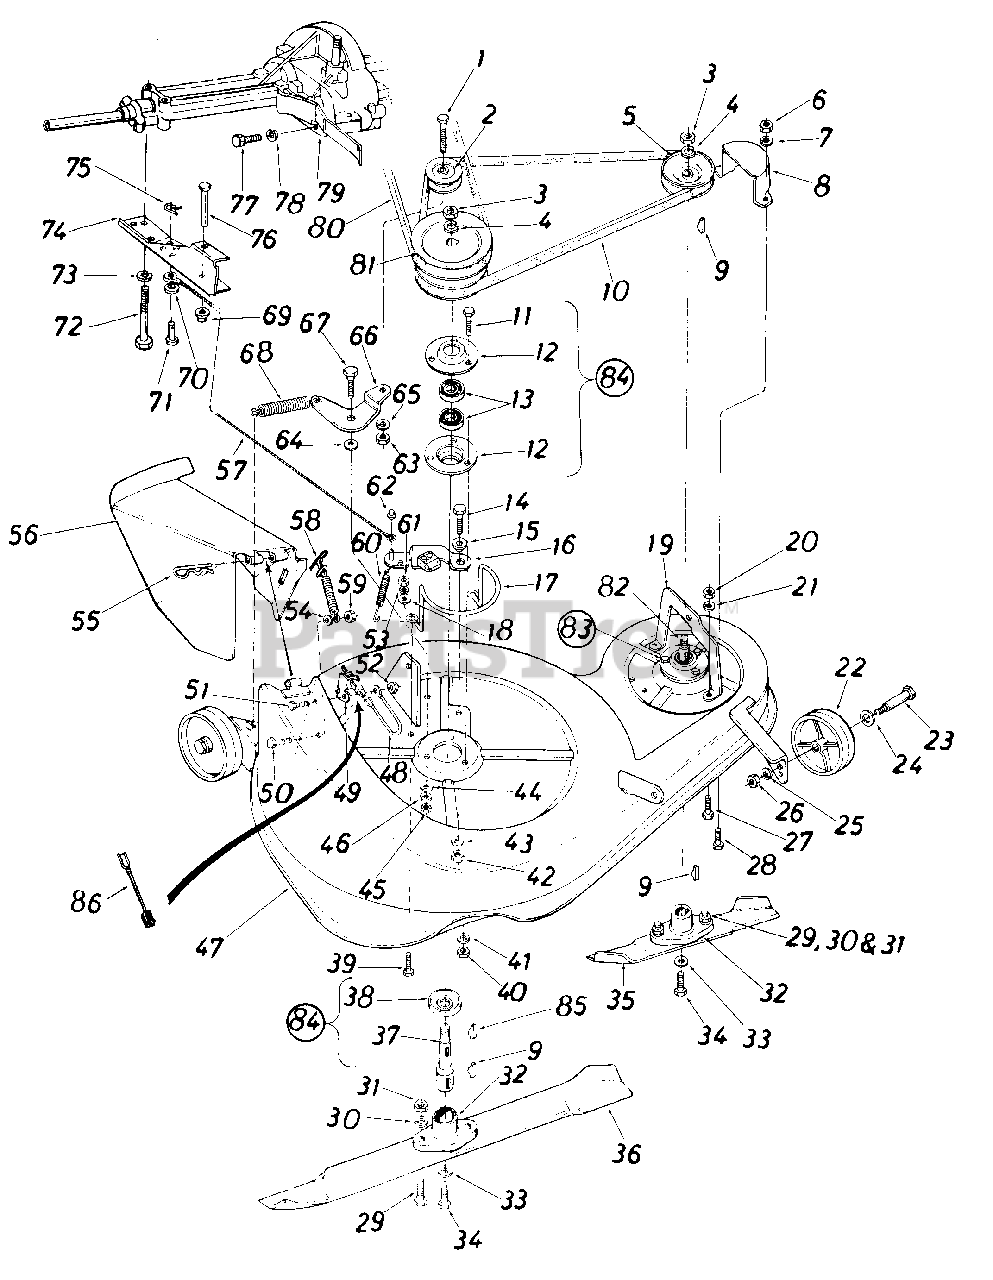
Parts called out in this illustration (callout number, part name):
1	Hex Bolt 3/8-24 x 1.50" Lg.
2	"V"-Idler Pulley 3.06" O.D.
3	Hex Jam Nut 5/8-18 Thd.
4	Bell-Wash. .630" I.D. x 1.25 x .090
5	Pulley 3.56" O.D. x 518
6	Hex Nut 1/4-20 Thd.
7	L-Wash. 1/4" I.D.
8	Belt Guard Cover
9	#6 Hi-Pro Key 5/32 x 518" Dia.
10	V-Belt 1/2 x 53" Lg. (4L)
11	Hex Bolt 5/16-18 x .75" Lg.
12	Brg. Housing 1.85" I.D.
13	Ball Bearing .787" I.D. x 1.85" O.D.
14	Hex Bolt 5/16-18 x 1.0" Lg. (Grade 5)
15	Shld. Spacer. 500" Dia. x .27" Lg.
16	Blade Brake Brkt. Ass'y.
17	Belt Guard
18	Fl-Wash. .344" I.D. x .875" O. D.
19	Deck Bracket
20	Hex Nut 5/16-18 Thd.
21	L-Wash. 5/16 I.D.
22	Deck Wheel 5.0" x 1.38"
23	Shoulder Bolt .498" Dia. x 1 .635
24	Belleville .400" I.D. x .88" O. D.
25	L-Wash. 3/8" I.D.
26	Hex Nut 3/8-16 Thd.
27	Hex Bolt 5/16-18 x .75" Lg.
28	Hex Bolt 1/4-20 x .62" Lg.
29	Hex Bolt 5/16-24 x 1.00" Lg. (Grade 5)
30	L-Wash. 5/16" I.D.
31	Hex Nut 5/16-24 Thd.
32	Blade Adapter
33	L-Wash. 3/8" I.D. H.D.
34	Hex Bolt 3/8-24 x 1.50" Lg. (Grade 5)
35	13" Blade
36	24" Blade
37	Blade Spindle 4.90" Lg.
38	Bearing Shield
39	Hex Bolt 5/16-18 x .75" Lg.
40	Hex Nut 5/16-18 Thd.
41	L-Wash. 5/16" I.D.
42	Hex Nut 5/16-18 Thd.
43	L-Wash. 5/16" I.D.
44	Hex Nut 5/16-18 Thd.
45	Hex Nut 5/16-18 Thd.
46	L-Wash. 5/16" I.D.
47	36" Deck Ass'y.
48	Ground Wire
49	Safety Switch
50	Truss Mach. Scr. 1/4-20 x .50" Lg.
51	Hex Bolt 1/4-20 x .62" Lg.
52	Hex Nut 1/4-20 Thd.
53	L-Wash. 5/16" I.D.
54	Fl-Wash. .281" I.D. x .50" O.D.
55	Internal Cotter Pin
56	Chute Deflector
57	Brake Cable Ass'y. 13.75" Lg.
58	Spring Latch Ass'y.
59	Hex Nut 1/4-20 Thd.
60	Extension Spring .38" O.D. x 3.25" Lg.
61	Hex Nut 5/16-18 Thd.
62	Cap Speed Nut 1/4" Rod
63	Hex Nut 3/8-16 Thd.
64	Fl-Wash. .344" I.D. x .875"O.D.
65	L-Wash. 3/8" I.D.
66	Deck Idler Brkt. Ass'y.
67	Shoulder Bolt .498" Dia. x .71
68	Extension Spring
69	Cap Speed Nut 1/4" Rod
70	Fl-Wash. .281" I.D. x .50"O.D.
71	Clevis Pin 1/4" Dia. x .53" Lg.
72	Hex Bolt 5/16-18 x 2.75" Lg.*
73	L-Wash. 5/16" I.D.
74	Lower Outside Belt Guard
75	Intern. Cot-Pin 5/16" Dia.
76	Weld Pin .25" Dia. x 2.5" Lg.
77	Hex Bolt 1/4-20 x .62" Lg.
78	L-Wash. 1/4" I.D.
79	Lower Inside Belt Guard
80	V-Belt 1/2 x 50" Lg.
81	Pulley 5.81 " O.D. x 5/8
82	Blade Spindle 3.70" Lg.
83	Spindle Ass'y.
84	Spindle Ass y.
85	#61 Hi-Pro Key 3/16" x 5/8" Dia.
86	Wire Lead
